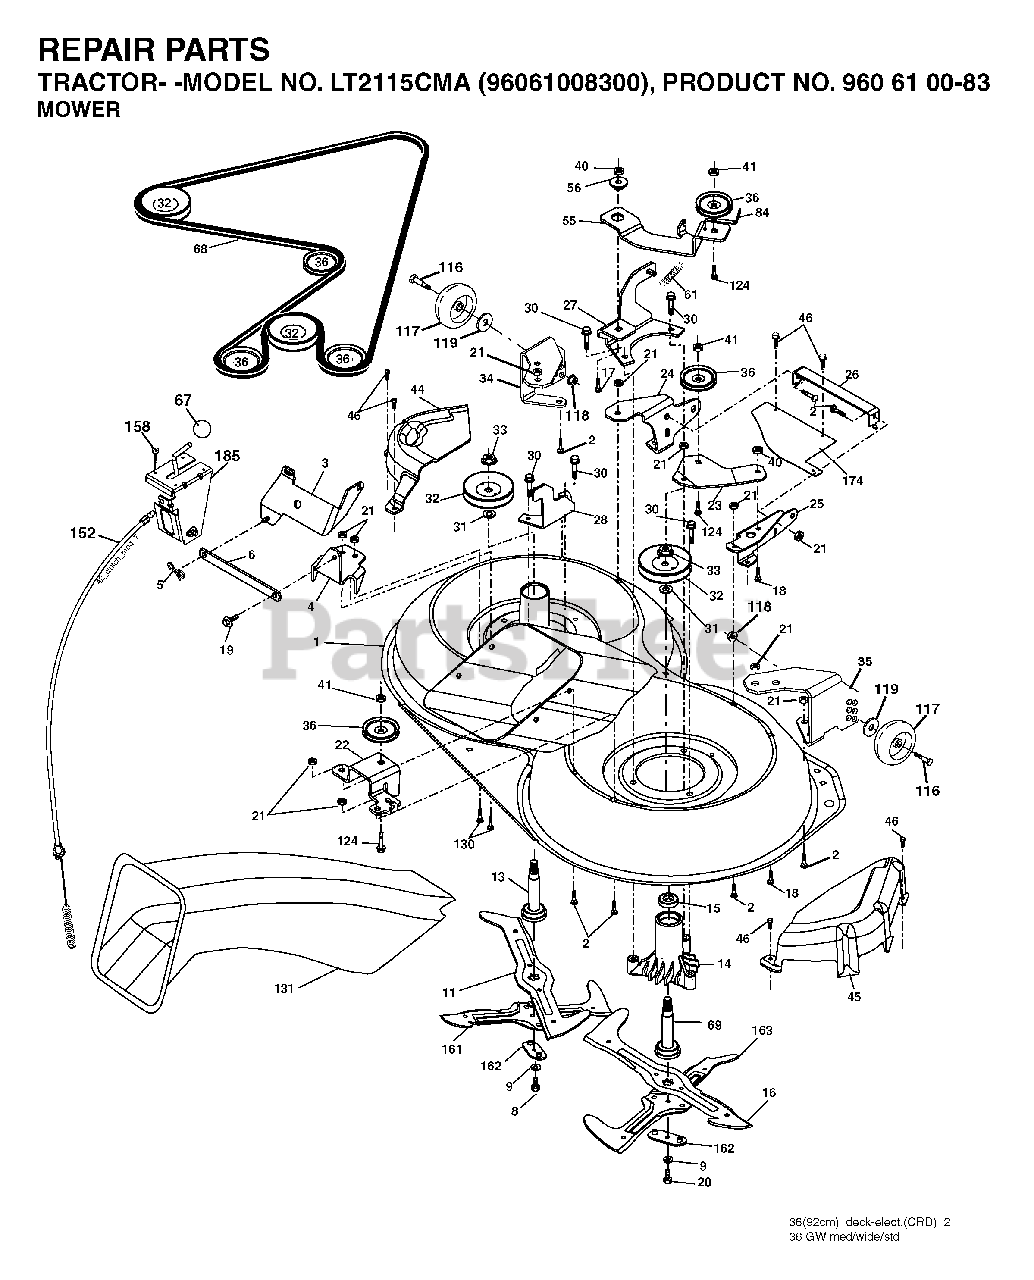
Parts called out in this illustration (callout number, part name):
2	BOLT
3	BRACKET
5	RETAINER-SPRNG RB
6	BAR SWAY
9	LOCKWASHER
13	SHAFT ASM VENT
14	HSG MANDREL
17	BOLT.3/8-14X1.25
19	BOLT SHD 5/16-18
21	LOCKNUT
24	BRACKET
25	BRACKET
28	BRACKET
30	SCREW, WASHER HEAD
31	WASHER.SPACER.MANDREL
33	NUT.FLANGE.LOCK.TOP
36	PULLEY.IDLER.4.25
40	LOCKNUT
41	NUT LOCK FLG 3/8-16 UNC
45	MANDREL COVER
46	SCREW.1/4-20X5/8
56	SPACER.RETAINER.MOWER
67	KNOB T (3/8 HOLE)
69	SHAFT.ASM.W/LWR.BRG.RH.THREAD
84	KEEPER, BELT IDLER
116	SHOULDER BOLT
117	WHEEL. GUAGE RALLY
118	LOCKNUT
119	WASHER
124	BOLT.3/8-16X1.50
131	CHUTE BAGGER
158	SCREW
169	COVER TERMINAL BATTERY
172	PUSH.NUT.ROUND.3/8.DIAM
173	NUT
185	HEAD ASM. CABLE CLUTCH
254	SCREW 3/8-16X1
